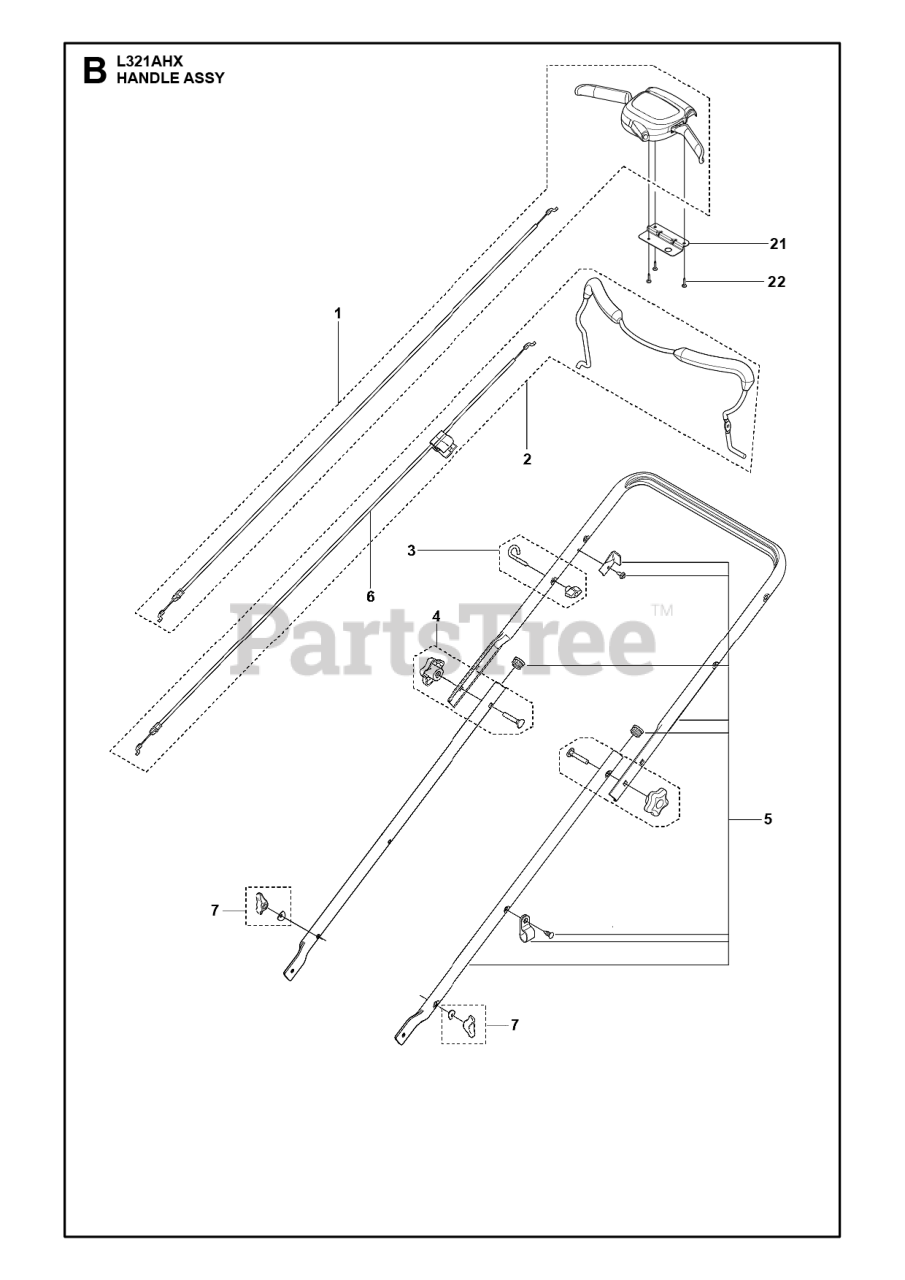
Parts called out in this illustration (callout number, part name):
1	CONTROL.AW2.AW/RG.BS.GY/BK.21E
2	Kits
4	Washers
5	Handles
6	CABLE.MZR.ZONE.CONTROL
7	KNOB
